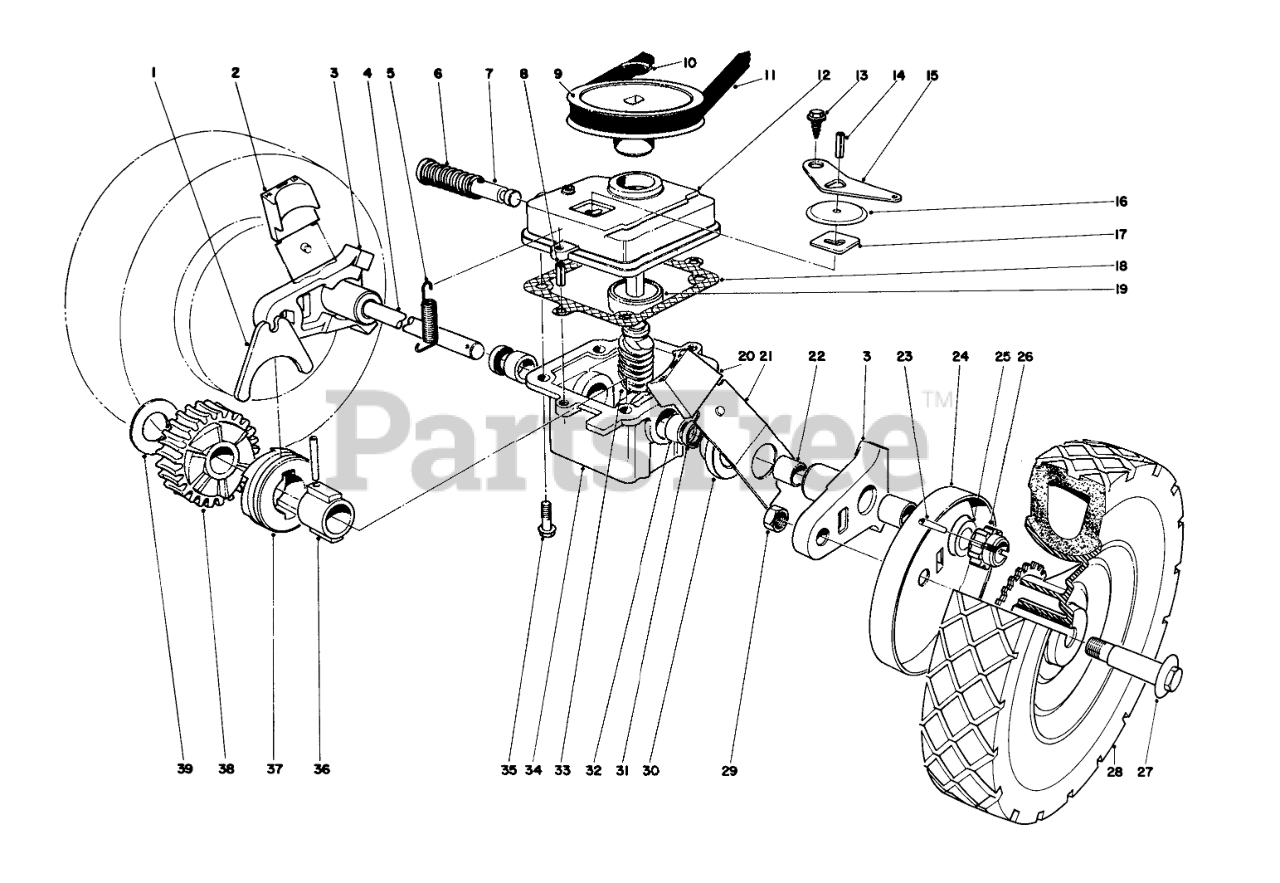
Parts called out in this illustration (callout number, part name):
1	SHIFTER FORK
2	Arm Knob
3	Pivot Arm (Incl. Ref. #22)
4	Drive Shaft
5	TENSION SPRING
6	SPRING
7	Shift Rod
8	3/16 X 1/2 ROLL PIN
9	PULLEY
10	PUSH-ON 93-3236
11	V BELT
12	GEAR CASE COVER
13	Screw
14	PIN-ROLL
15	SHIFTER ARM
16	TRANS DUST COVER
17	LATCH PLATE
18	GASKET
19	Ball Bearing
20	Arm Knob
21	Spring Arm
22	BUSHING
23	COIL PIN
24	WHEEL COVER
25	WASHER-THRUST
26	Pinion
28	Wheel & Tire
29	Nut
30	End Cap
31	Seal
32	Bushing
33	WORM SHAFT
34	Gear Case
35	Screw
36	SLEEVE
37	CLUTCH JAW
39	THRUST WASHER
